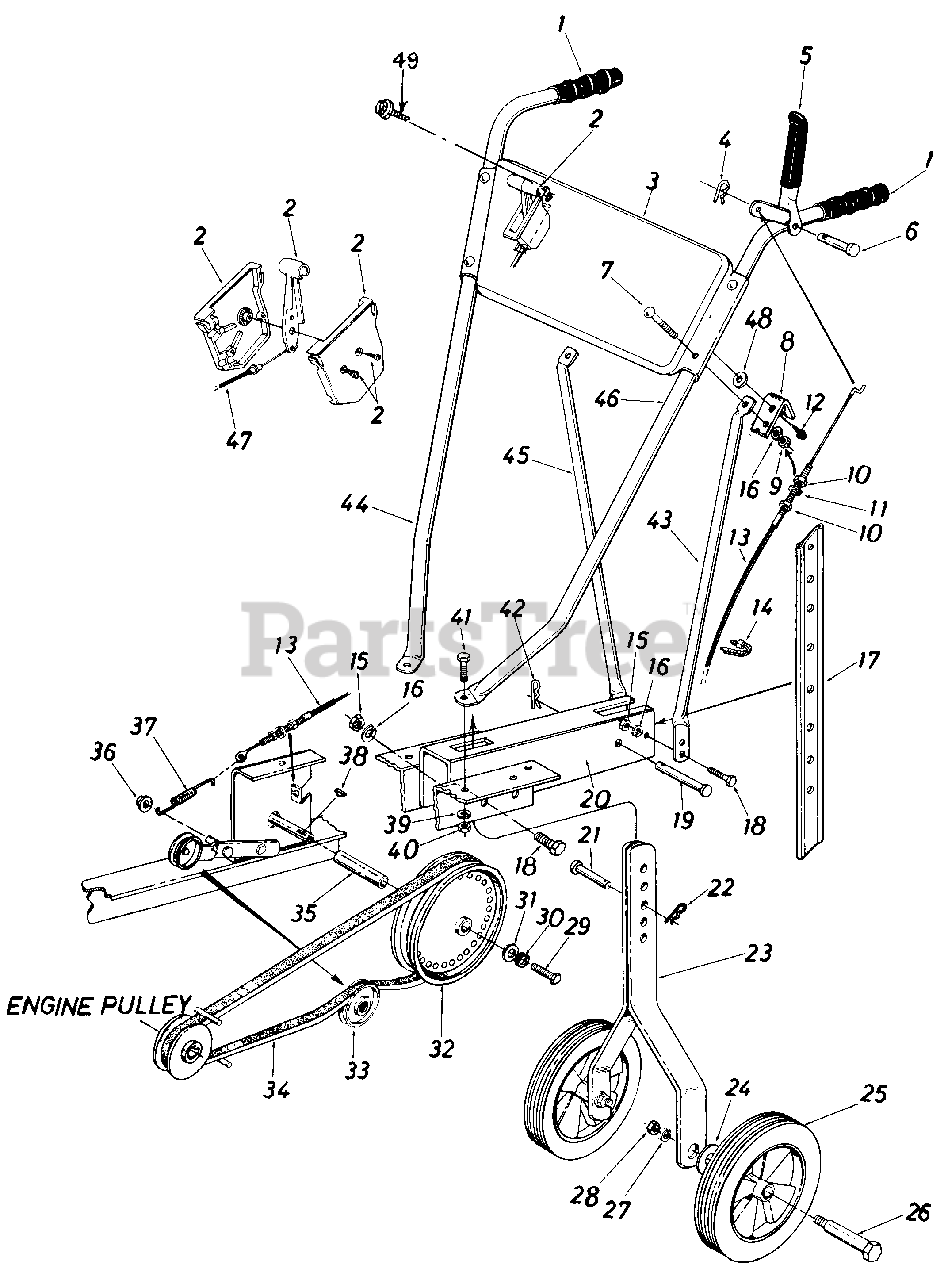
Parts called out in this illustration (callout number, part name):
2	Throttle Control Box
3	Handle Panel
4	Int. Cotter Pin
5	Clutch Grip Ass'y.
6	Clevis Pin
7	Carriage Bolt 5/16-18 x 1.75" Lg.*
8	Cable Support Brkt.
9	Hex Nut 5/16-18 Thd.*
10	Hex Jam Nut 5/16-24 Thd.
11	L-Wash. 5/16" I.D.*
12	Hex Wash. Hd. Self-Tap Scr. 1/4-20 x .50" Lg.
13	Clutch Control Cable
14	Cable Tie
15	Hex Nut 5/16-18 Thd.*
16	L-Wash. 5/16" I.D.*
17	Depth Bar
18	Hex Bolt 5/16-18 x .75" Lg.*
19	Clevis Pin 1/2" Dia. x 2.50" Lg.
20	Tailpiece Ass'y.
21	Clevis Pin 3/8" Dia. x 2.50" Lg.
22	Hairpin Cotter
23	Wheel Bracket Ass'y.
24	Belleville Wash. 1/2" I.D.
25	Wheel Ass'y. 9 x 1.75
26	Shoulder Bolt
27	L-Wash. 1/2" I.D.
28	Hex Nut 1/2-20 Thd.
29	Hex Bolt 1/4-28 x .75" Lg.
30	L-Wash. 1/4" I.D.
31	Fl-Wash. .25" I.D. x .930" O.D.
32	Pulley 6.00" O.D.
33	Idler Pulley
34	"V"-Belt 1/2" Pitch x 39" Lg.
35	Spacer
36	Cap Speed Nut
37	Extension Spring
38	Hi-Pro Key
39	L-Wash. 5/16" I.D.
40	Hex Nut 5/16-18 Thd.*
41	Hex Bolt 5/16-18 x .75" Lg.
42	Hairpin Cotter
43	Handle Support Bracket- L.H.
44	Handle Bar-R.H.
45	Handle Support Bracket- R.H.
46	Handle Bar-L.H.
47	Throttle Control Cable-35"
48	Fl-Wash. .281" I.D. x .50" O.D.
49	Self-Tap Scr. #10 x 1/2" Lg.
